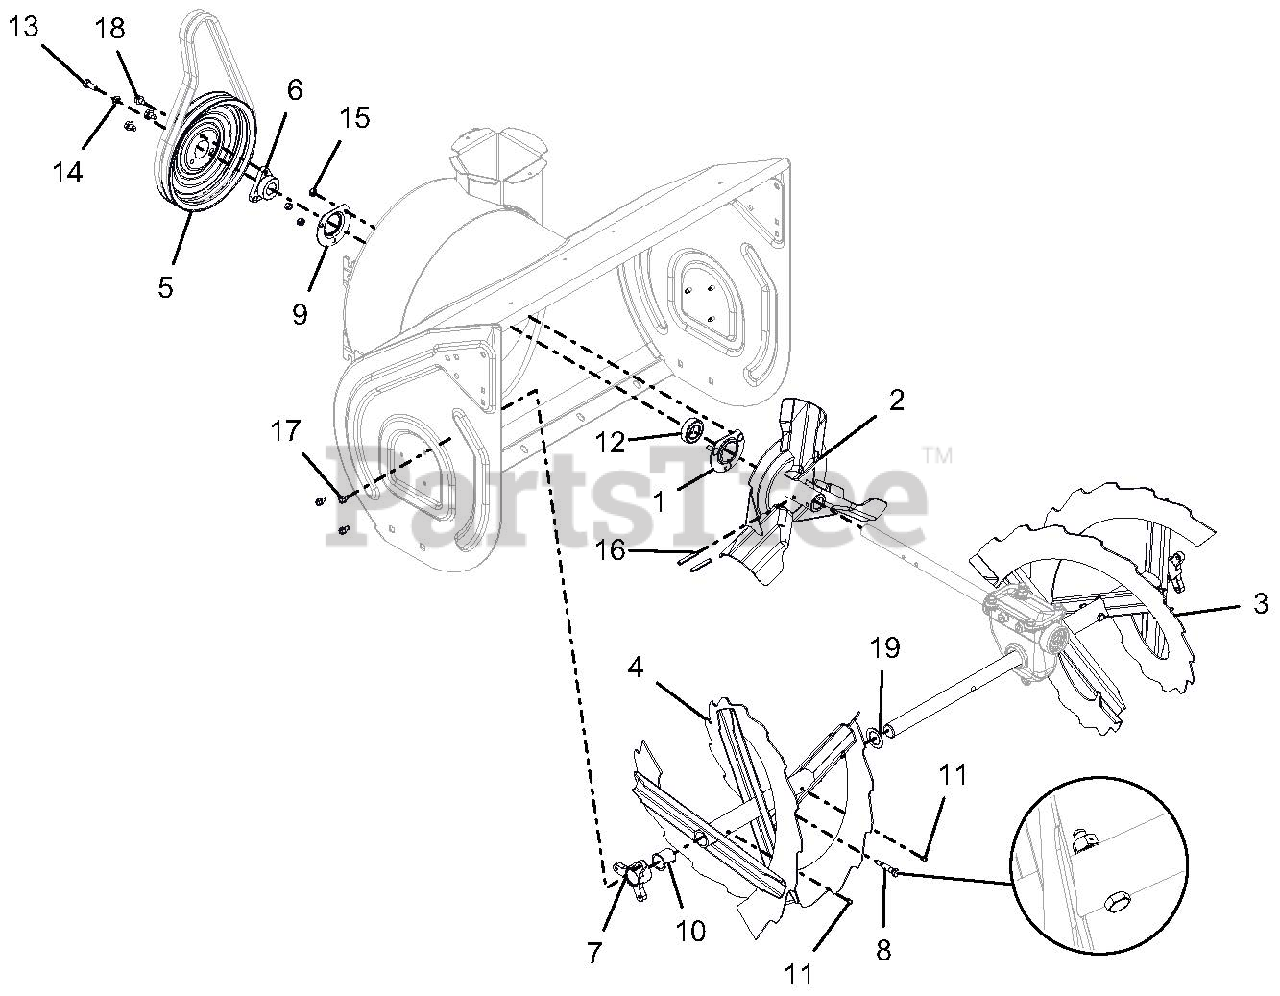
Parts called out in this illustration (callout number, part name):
1	BEARING FLANGE
2	IMPELLER, 3 BLADE-14"
3	RAKE, LH-28"(1 ID X 15.75 OD)
4	RAKE, RH-28"(1 ID X 15.75 OD)
5	PULLEY, SPIN FORM DUAL GROOVE
6	PULLEY HUB, D-BORE .87 PRO
7	BUSHING, RAKE SHAFT 1"
8	SHEAR BOLT SERVICE ASSEMBLY
9	BEARING FLANGE
10	BSHG-FLG SPLIT NYLINER 1.0" HP
11	ZERK,FITTING .25X.125 DRIVE IN
12	BRG-BALL .876X1.75X.50 RSTFP
13	BLT-HEX .31-24X.75 YWZC GR5
14	WSHR-LK .312X.097 HVY YWZC
15	@NUT-LK-CTR .25-20 YWZC
16	PIN-ROLL .250X1.75
17	SCR-TAP .25-20X.50 HWH TR YWZ
18	@SCR-TAP .31-18X.50 HWH TR YWZ
19	WSHR-FL-STL 1.010X1.505X.062YZ
